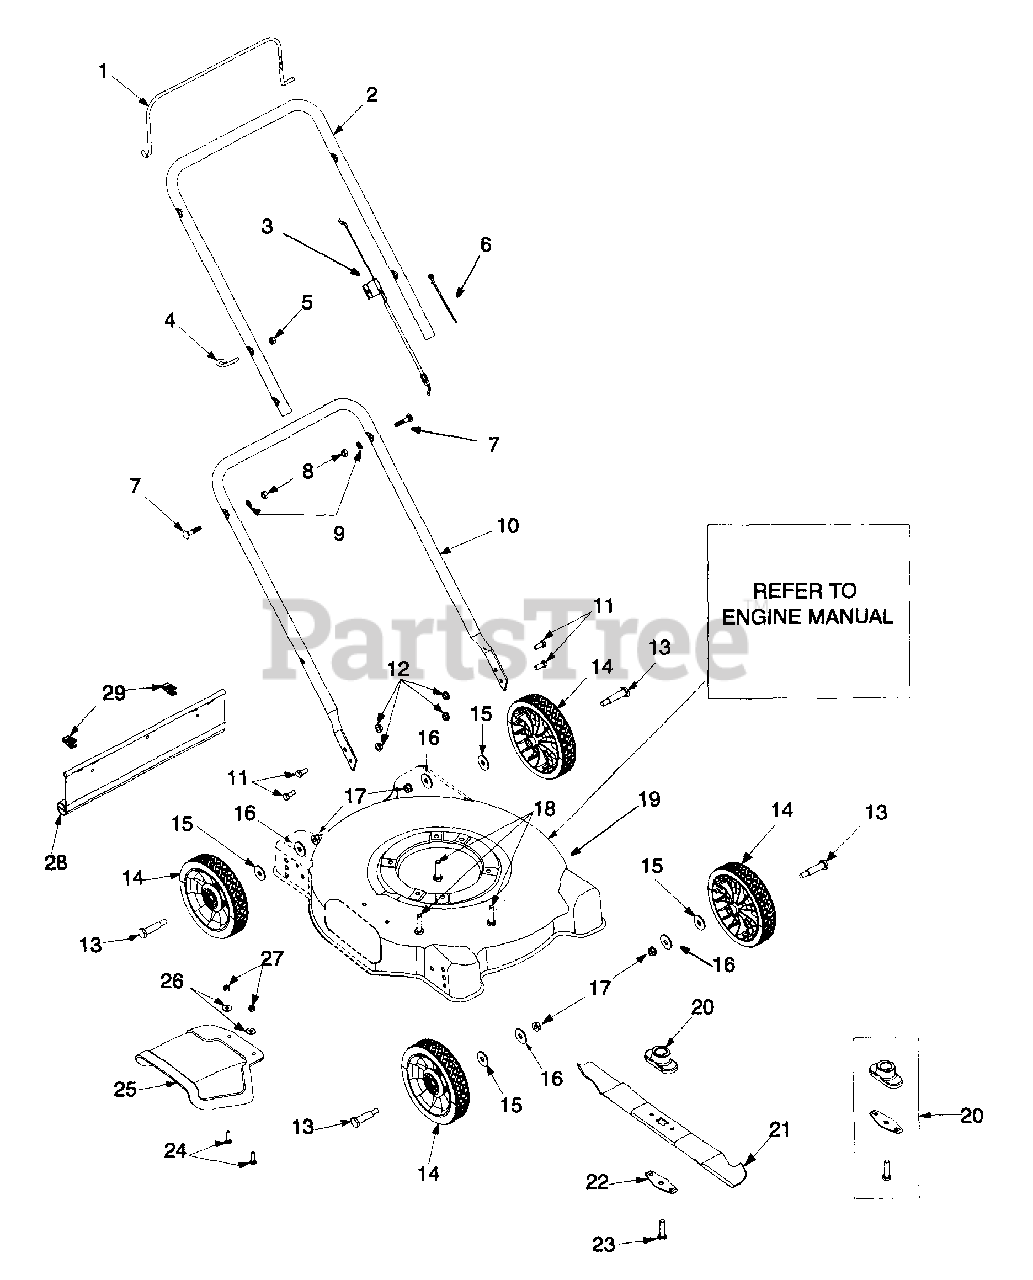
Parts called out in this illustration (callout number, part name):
4	Eye Bolt 1/4-20
5	Lock Nut 1/4-20 Thd.
6	Cable Tie
7	Carriage Bolt 5/16-18 x 1.5" Lg.
8	Nut 5/16-18 Thd.
9	Lock Washer 5/16
12	Lock Nut 5/16-18 Thd.
13	Shoulder Screw .498" x 1.635"
14	Wheel 7 x 1.5" Star Diamond Trd.
15	Bell Washer .401" ID x .87" OD
16	Bell Washer .39" ID x 1.13" OD
17	Fl. Lock Nut 3/8-16 Thd.
18	Hex Screw w/LWsh. 3/8-16 x 1.0" Lg.
21	Blade
22	Support: Blade Bell
23	Screw 3/8-24 x 1.5" Lg. - Gr8
24	Carriage Screw 1/4-20 x 1.0" Lg.
25	Discharge Chute
26	Flat Washer .28" ID x .74" OD
27	Lock Nut 1/4-20 Thd.
28	Trail Shield
29	Hinge Clip
